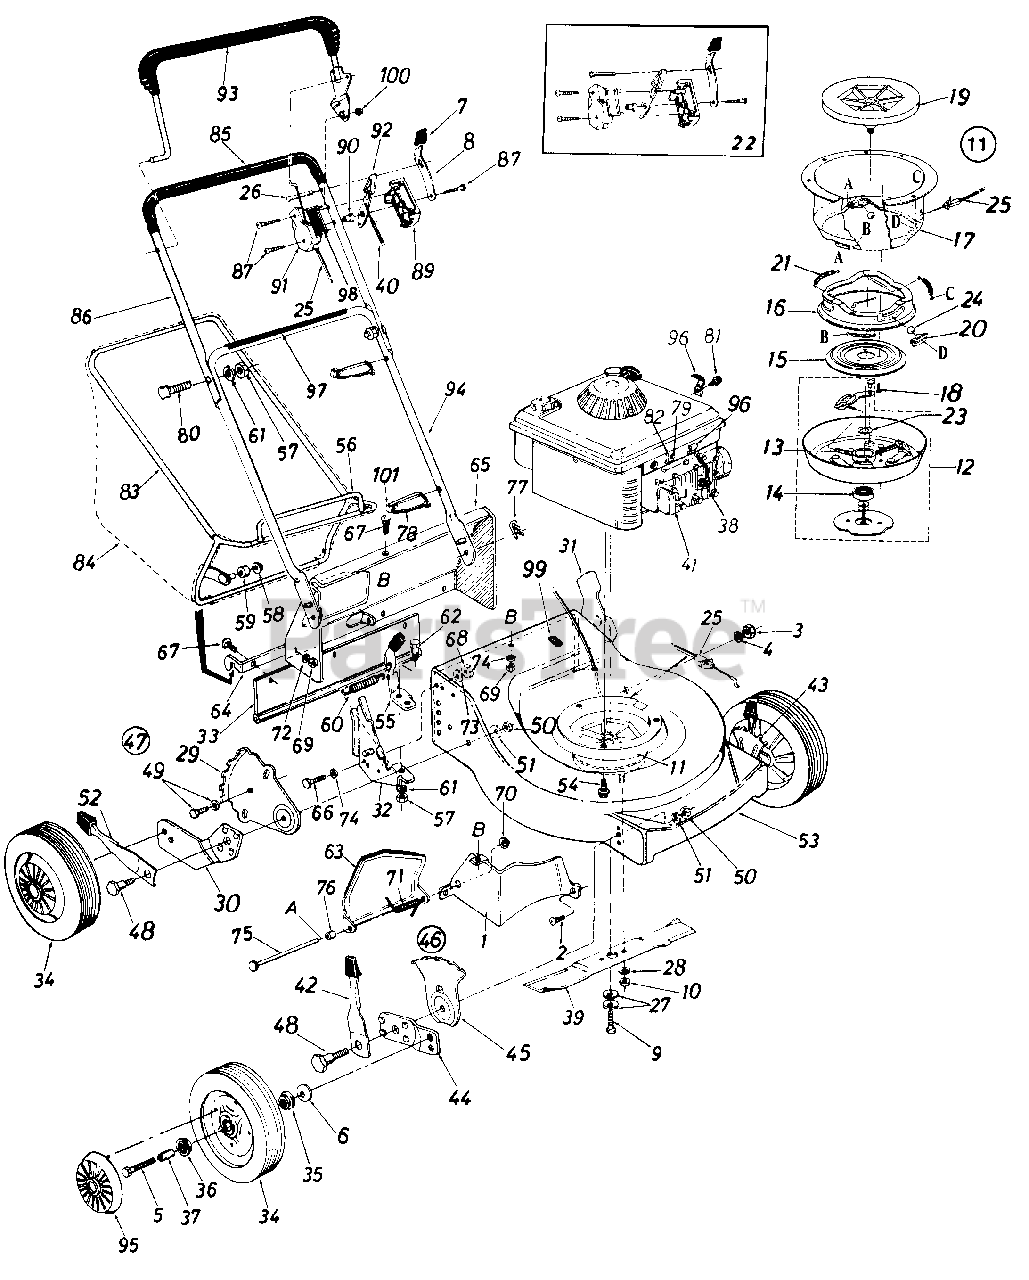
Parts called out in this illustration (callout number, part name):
1	Rear Baffle
2	Carriage Bolt 1/4-20 x .50" Lg.
3	Hex Nut 1/4-20 Thd.
4	L-Wash. 1/4" I.D.
5	Axle Bolt
6	Bell-Wash. .400" I.D. x .88"
7	Spring Lever Knob
8	Lockout Spring
9	Hex Scr. 3/8-24 x 2.00" Lg. (Grade 8)
10	Hex Nut 3/8-24 Thd. (Grade 8)
11	Blade Brake/Clutch Ass'y. Comp.
12	Clutch Blade Housing Ass'y.
13	Compression Spring
14	Ball Brg. .669" I.D. x 1.574" O.D.
15	Clutching Cone
16	Brake Cup Cone
17	Clutch Housing
18	Hex Tap L-Scr. 1/4-20 x .75"
19	Fan Adapter
20	Ball Block
21	Extension Spring
22	Control Housing Comp.
23	Fl-Wash. .690" I.D. x 1.060" O.D.
24	Steel Ball .500" Dia.
25	Clutch Cable-46.0"
26	Lock Pin .314" Dia. x 1.70" Lg.
27	Bell-Wash. .400" I.D. x .88"
28	L-Wash. 3/8" I.D.
29	Rear Index Plate
30	Rear Pivot Bar-R.H.
31	Handle Brkt. Ass'y.-L.H.
32	Handle Brkt. Ass'y.-R.H.
33	Rear Flap Ass'y.
35	Bearing
36	Bearing
37	Spacer
38	Spark Plug Insulator
39	21" Blade
40	Throttle Wire-58" (Black)
41	Engine
42	Spring Lever w/Knob
43	Front Height Adj. Ass'y.-L.H.
44	Front Pivot Bar
45	Front Index Plate
46	Front Height Adj. Ass'y.-L.H.
47	Rear Height Adj. Ass'y.-R.H.
48	Shld. Bolt .500" Dia. x .375
49	Hex Wash. Hd. Tap Scr. 1/4 x.62" Lg.
50	Hex Nut 3/8-16 Thd.
51	Bell-Wash. .39" I.D. x 1.38"
52	Spring Lever w/Knob
55	Grass Catcher Lock Lever
58	Push Nut 3/8" Rod
59	Plastic Roller
60	Tension Spring
61	L-Wash. 5/16" I.D.*
62	Shld. Bolt .437" Dia. x .162" Lg.
63	Chute Door
64	Grass Catcher Hitch Brkt.
65	Rear Discharge Deck Section
66	Hex Bolt 1/4-28 x .75" Lg.
67	Carr. Bolt 1/4-20 x .75" Lg.
68	Hex Nut 1/4-28 Thd.
69	Sems Nut 1/4-20 Thd.
70	Push Nut 1/4" Rod
71	Torsion Spring
72	Fl-Wash. .285" I.D. x 1.25" O.D.
73	Bell-Wash. 1/4" I.D. x .88" O.D.
74	L-Wash. 1/4" I.D.
75	Hinge Pin .250" Dia. x 7.88" Lg
76	Spacer .262" I.D. x .31" O.D.
77	Intern. Cot. Pin 5/16" Dia.
78	Cable Tie
79	Hex B-Tap Scr. #10 x .62"
80	Curved Carriage Bolt 5/16-18 x 1.38" Lg.
81	Hex B-Tap Scr. #10 x .38" Lg.
82	Casing Clamp
83	Grass Catcher Upper Frame
84	Grass Bag (Without Flip Top)
86	Upper Handle (Chrome)
87	Truss Mach. Hl-B Tap Scr. #12 x 1.50" Lg.
89	Control Panel Half
90	Control Disc Pin
91	Clutch Panel Half
92	Throttle Control Lever
93	Control Handle-L.H.
94	Lower Handle (Chrome)
95	Hub Cap
96	Casing Clamp
97	Instruction Label-Handle
98	Control Label-Throttle
99	Plastic Plug
100	Push Cap
101	Cable Anchor
